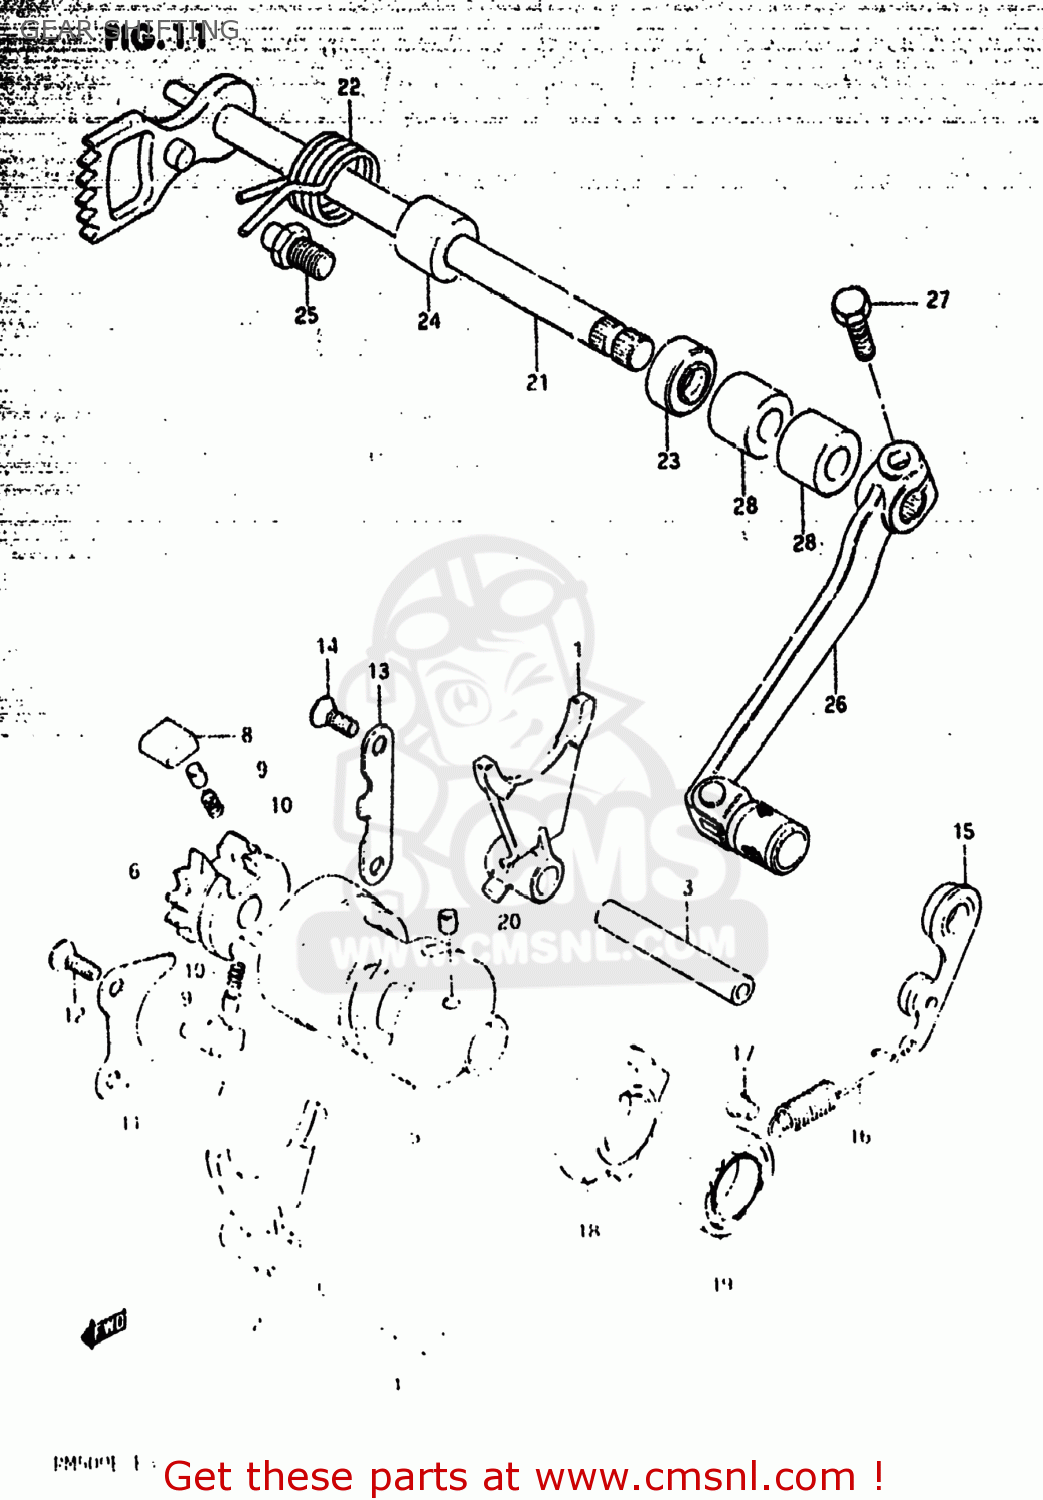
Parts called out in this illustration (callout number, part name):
1	FORK,GEAR SHIFT NO.1
2	FORK,GEAR SHIFT NO.2
3	SHAFT,GEAR SHIFT FORK
4	SHAFT,GEAR SHIFT FORK
5	CAM,GEAR SHIFT
6	RETAINER,GEAR SHIFT CAM
7	PAWL,GEAR SHIFT NO.1
8	PAWL,GEAR SHIFT NO.2
9	PIN(5X8)
10	SPRING
11	LIFTER,GEAR SHIFT PAWL
12	SCREW
13	STOPPER,GEAR SHIFT POLE
14	SCREW
15	STOPPER,GEAR SHIFTING
16	SPRING
17	RIVET
18	PLATE,GEAR SHIFT CAM STOPPER
19	BEARING
20	PIN
21	SHAFT,GEAR SHIFT
22	SPRING
23	OIL SEAL
24	SPACER(12X20X15.3)
25	STOPPER,GEAR SHIFT CAM
26	LEVER ASSEMBLY,GEAR SHIFTING
27	BOLT
28	SPACER(12X20X15.3)
